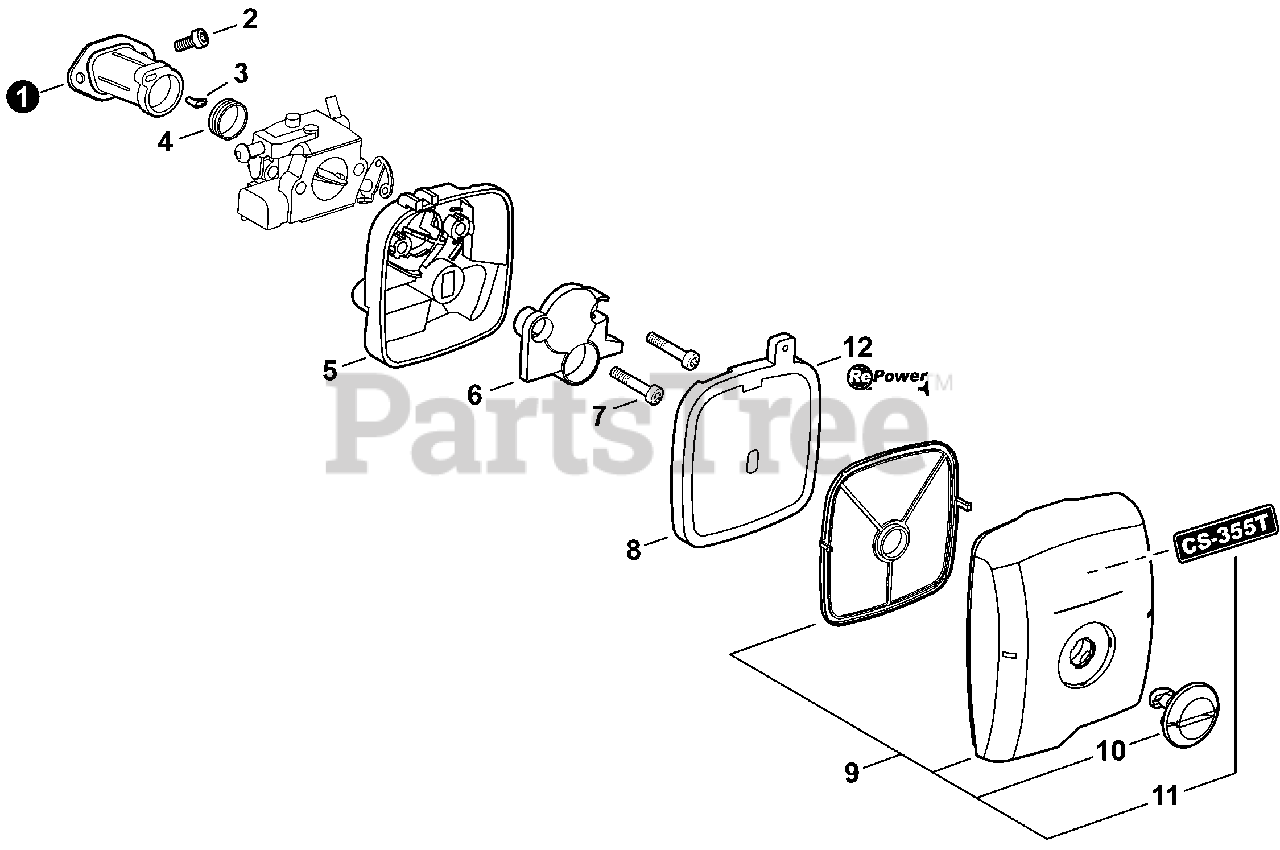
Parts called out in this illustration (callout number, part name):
1	BELLOWS, INTAKE
2	BOLT, TORX 5×12
3	COLLAR Ø3.2×6.5
4	SPRING, TENSION
5	CASE, AIR FILTER
6	PLATE, PREVENT
7	BOLT, TORX 5×50
8	FILTER, AIR
9	COVER ASSY, AIR FILTER
10	KNOB, AIR FILTER COVER
11	LABEL - MODEL CS-355T
12	TUNE-UP KIT - REPOWER
